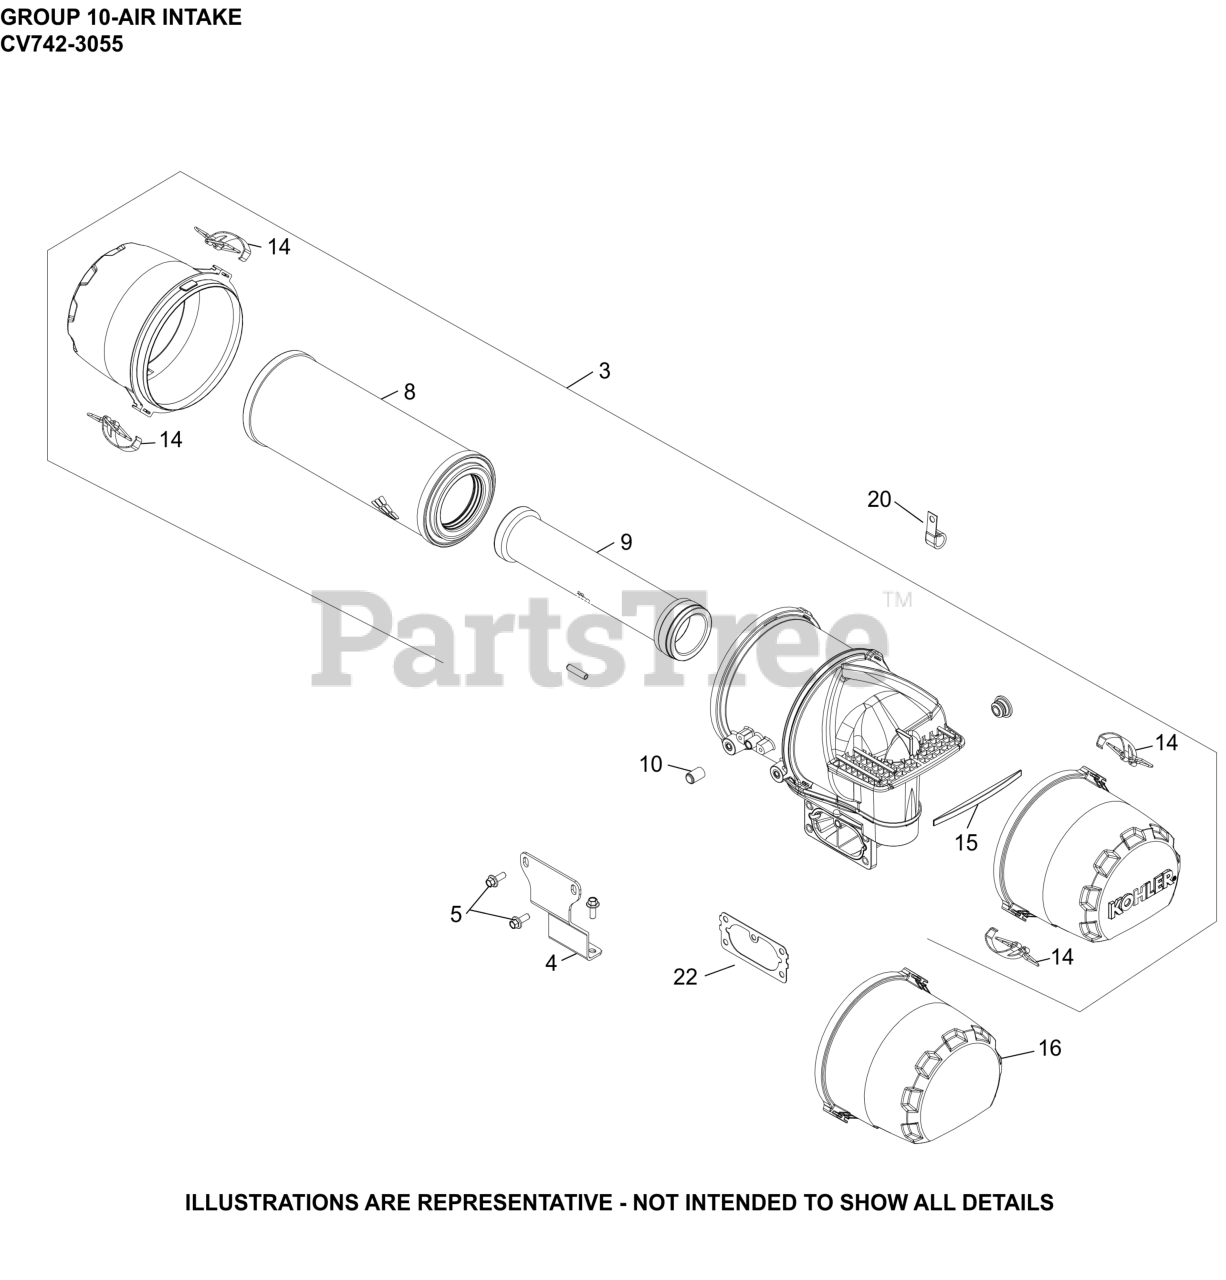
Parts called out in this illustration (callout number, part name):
3	FILTER AIR ASSEMBLY, OIL FILTER SIDE
4	BRACKET, SUPPORT
5	SCREW, FLG M6X1.0X16
8	ELEMENT, AIR FILTER - PRIMARY
9	ELEMENT, AIR FILTER - SAFETY
10	CAP, MASKING
14	CLIP ASSEMBLY
15	DAMPER, FOAM INSERT
16	COVER, AIR FILTER W/O LOGO
16	COVER, RAIN CAP W/O LOGO
20	CLIP, CABLE (KM)
22	GASKET, AIR CLEANER
